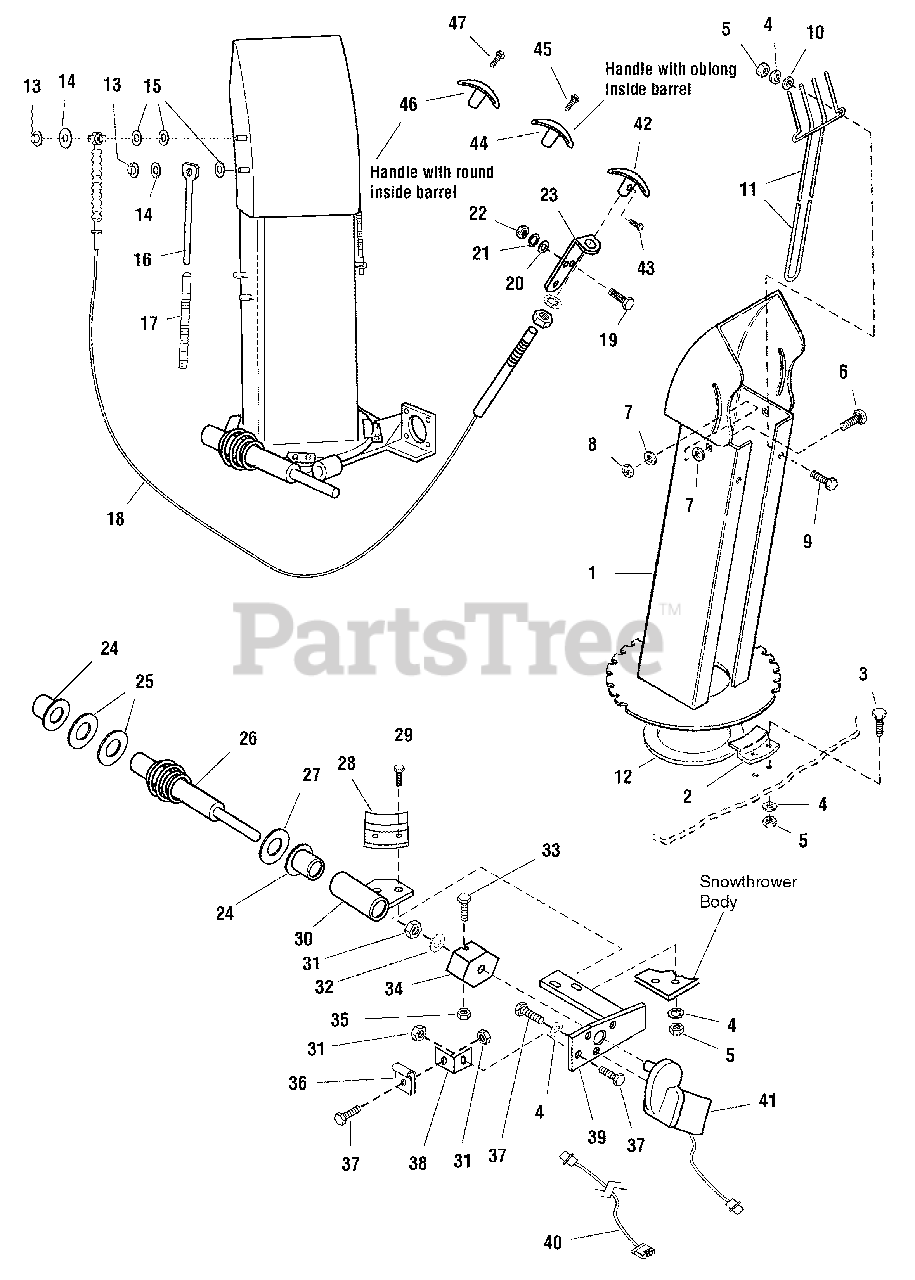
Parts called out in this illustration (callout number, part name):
1	CHUTE ASSEMBLY (w/ Deflector)
2	RETAINER, Chute
3	CAPSCREW, Hex Head, 1/4-20 x 1/2
4	WASHER, Lock, 1/4
5	NUT, Hex, 1/4-20
6	CARRIAGE BOLT, 5/16-18 x 3/4
7	WASHER, 5/16
8	NUT, Hex Nylon Lock, 5/16-18
9	CAPSCREW, Hex Head, 1/4-20 x 3/4
10	WASHER, 1/4
11	GUARD, Chute
12	GASKET, Chute
13	NUT, Push, 1/4
14	WASHER, 1/4
16	ROD, Spring, 5/16
17	SPRING, Compression
18	CABLE ASSEMBLY
19	CAPSCREW, Hex Head, 1/4-20 x 7/8
20	WASHER, 1/4
21	WASHER, Lock, 1/4
22	NUT, Hex, 1/4-20
23	BRACKET, Cable Mounting
24	BUSHING, Turn Collar
25	WASHER, 3/4
26	WORM GEAR ASSEMBLY
27	WASHER, 3/4
28	RETAINER, Chute
29	CAPSCREW, Hex Head, 1/4-20 x 3/4
30	BRACKET, Support
31	NUT, Hex Lock,1/4-20
32	WASHER, 1/4
33	SCREW, Truss Head, Phillips, 1/4-20 x 1-5/8
34	ADAPTER, Motor
35	NUT, Hex Nylon Lock, #10-24
36	CLAMP, Cable, 1/4
37	CAPSCREW, Hex Head, 1/4-20 x 7/8
38	BRACKET
39	SUPPORT ASSEMBLY
40	WIRE HARNESS
41	MOTOR, Electric
43	SCREW, Set, Hex #10-24 x 3/8
44	HANDLE "T"
45	SCREW, #8c x 3/4
46	HANDLE "T"
47	SCREW, Round Head
